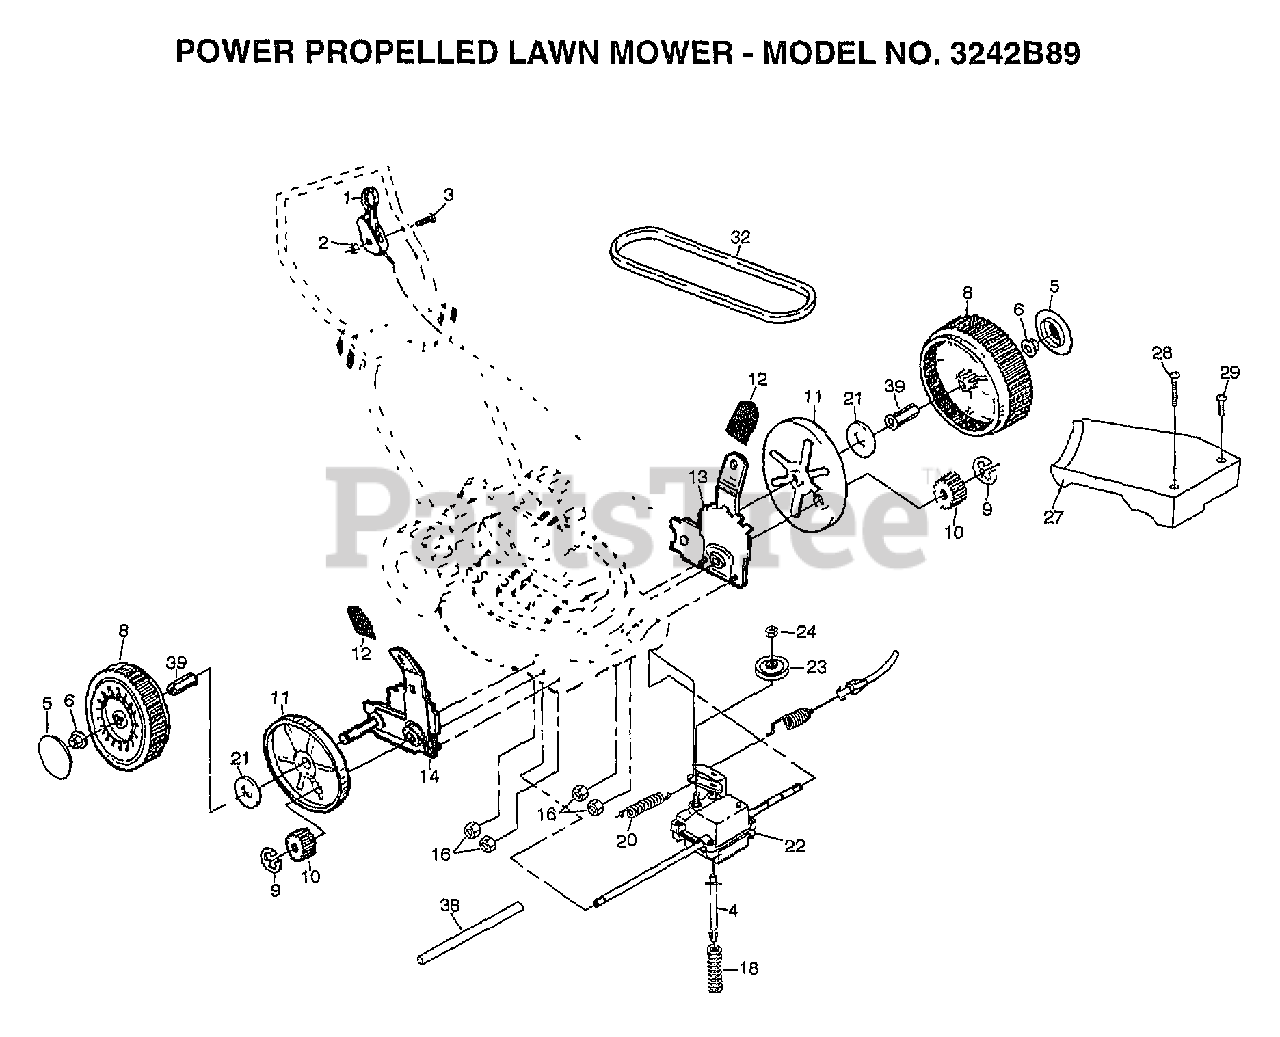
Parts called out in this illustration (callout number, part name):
1	CONTROL.DRV.56.25
2	LOCKNUT
3	PAN HEAD SCREW
4	SPRING.RETAINER.
5	HUB CAP
6	NUT.HXFLG.LOCK.
8	WHEEL.8X2.LP.PR
9	E-RING.7/16.RE.
10	PINION.GEAR
11	DUST SHROUD PM
12	KNOB PM
13	WHEEL.ADJ.ASM.LH.
14	WHEEL.ADJ.ASM.RH.
18	SPRING.TENSION
20	SPRING
21	WASHER FLUT
23	PULLEY.DRIVEN
24	LOCKNUT
27	COVER DRIVE BLK
28	SCREWL.SLOT.TORXT
29	SCREW.SLOT.TORTX.
38	DRV SHAFT TUBE PM
39	BUSHING.HEX
